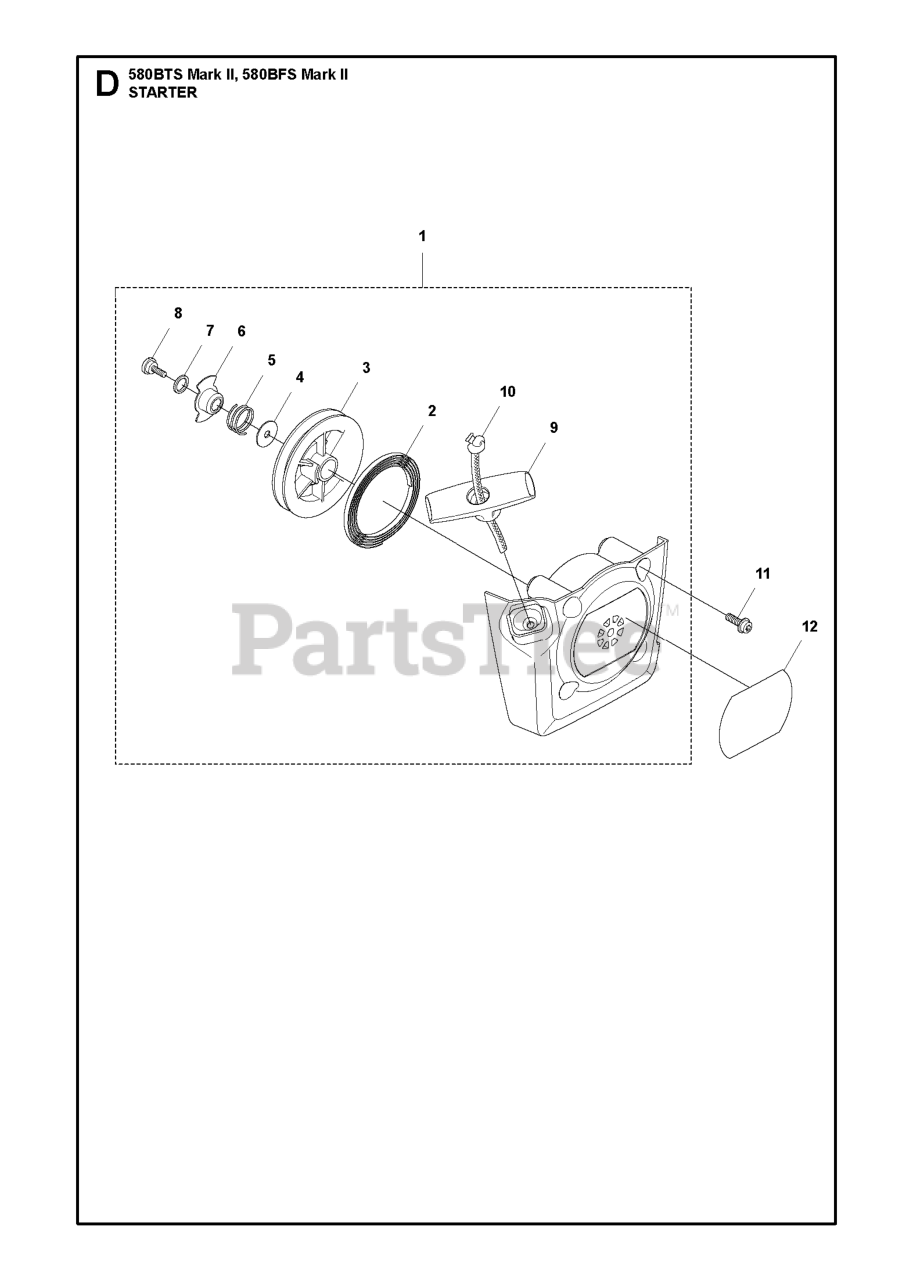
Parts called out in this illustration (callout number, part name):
1	STARTER ASSY
4	WASHER
5	SPRING FRICTION
12	DECAL
12	DECAL STARTER 580BFSMKII
